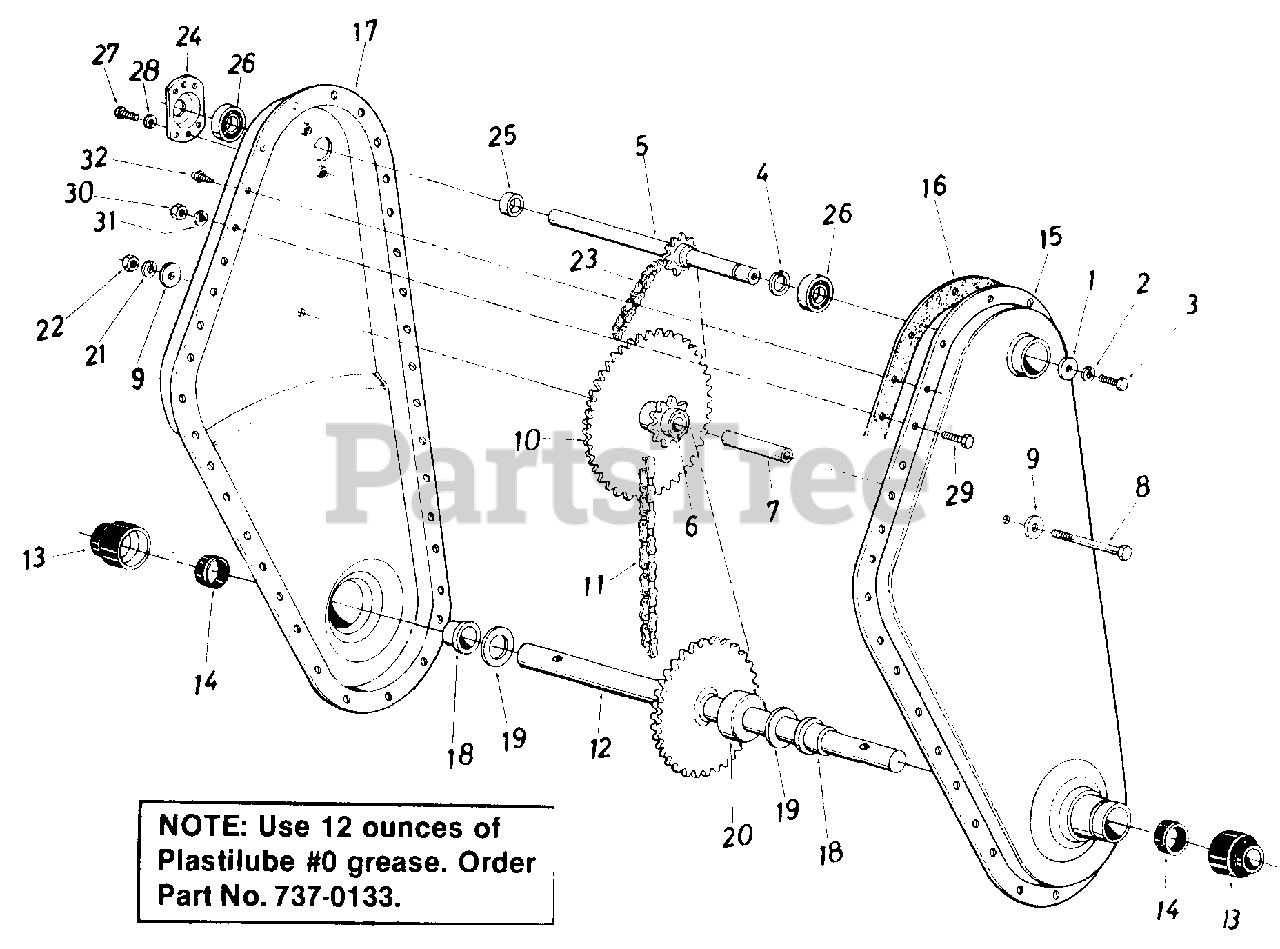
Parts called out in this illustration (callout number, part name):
1	Fl-Wash. 1/4" I.D. x .93" O.D. x .120
2	L-Wash. 1/4" I.D.
3	Hex Bolt 1/4-28 x .62" Lg. w/Patch
4	External Snap Ring - 5/8" Dia.
5	Input Shaft Ass'y.
6	Bearing 5/8" I.D. x 3/4" O.D. x 1.860" Lg.
7	Sprocket Hub Tubing 3/8" I.D. x 5/8" O.D. x 1.90
8	Hex Bolt 3/8-24 x 2.75" Lg.
9	Fl-Wash. 3/8" I.D. x 1.25" O.D. x .10
10	Sprocket Ass'y.
11	#50 Chain 5/8" Pitch x 46 Links Endless
12	Tine Shaft Ass'y.
13	Dust Cup
14	Seal Ring Single Lip, Springless
19	Fl-Thrust Wash. 1.0" I.D. x .03 Thk.
20	Step Spacer
21	L-Wash. 3/8" I.D.
22	Hex Nut 3/8-24 Thd.
23	#35 Chain 3/8" Pitch x 52 Links Endless
24	Bearing Housing 1.38" I.D.
26	Ball Bearing .625" I.D. x 1.38" O.D. x .437
27	Hex Wash. SF-Tap Scr. 1/4-20 x .50" Lg.
28	L-Wash. 1/4" I.D.
29	Hex Bolt 5/16-18 x .75" Lg.
30	Hex Nut 5/16-18 Thd.
31	L-Wash. 5/16" I.D.
32	Hex Wash. SF-Tap Scr. 1/4-20 x .50" Lg.
